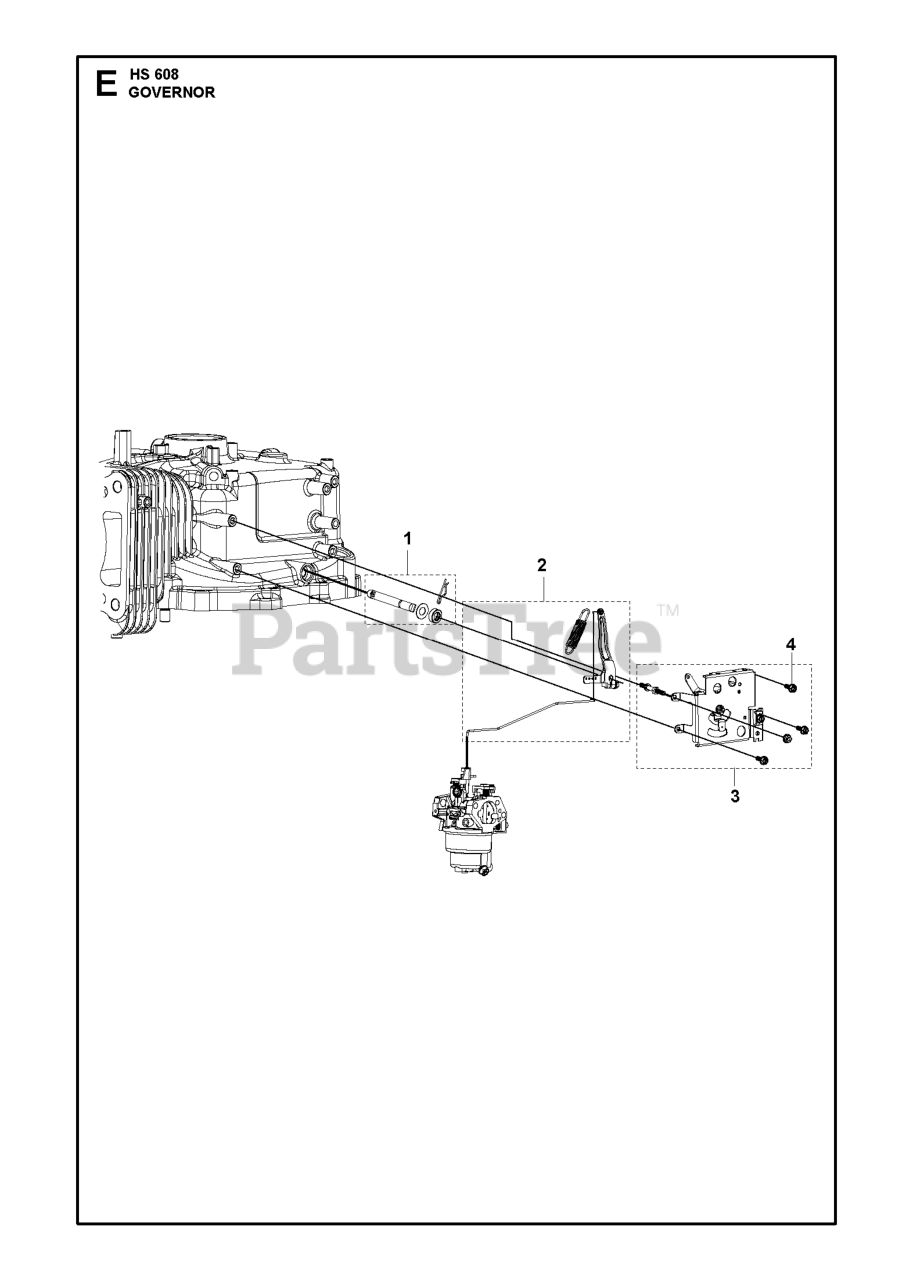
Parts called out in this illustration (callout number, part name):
1	SERVICE KIT KIT.SPEED REGULATI
2	THROTTLE ASSY
3	THROTTLE HANDLE
4	Husqvarna TBD
